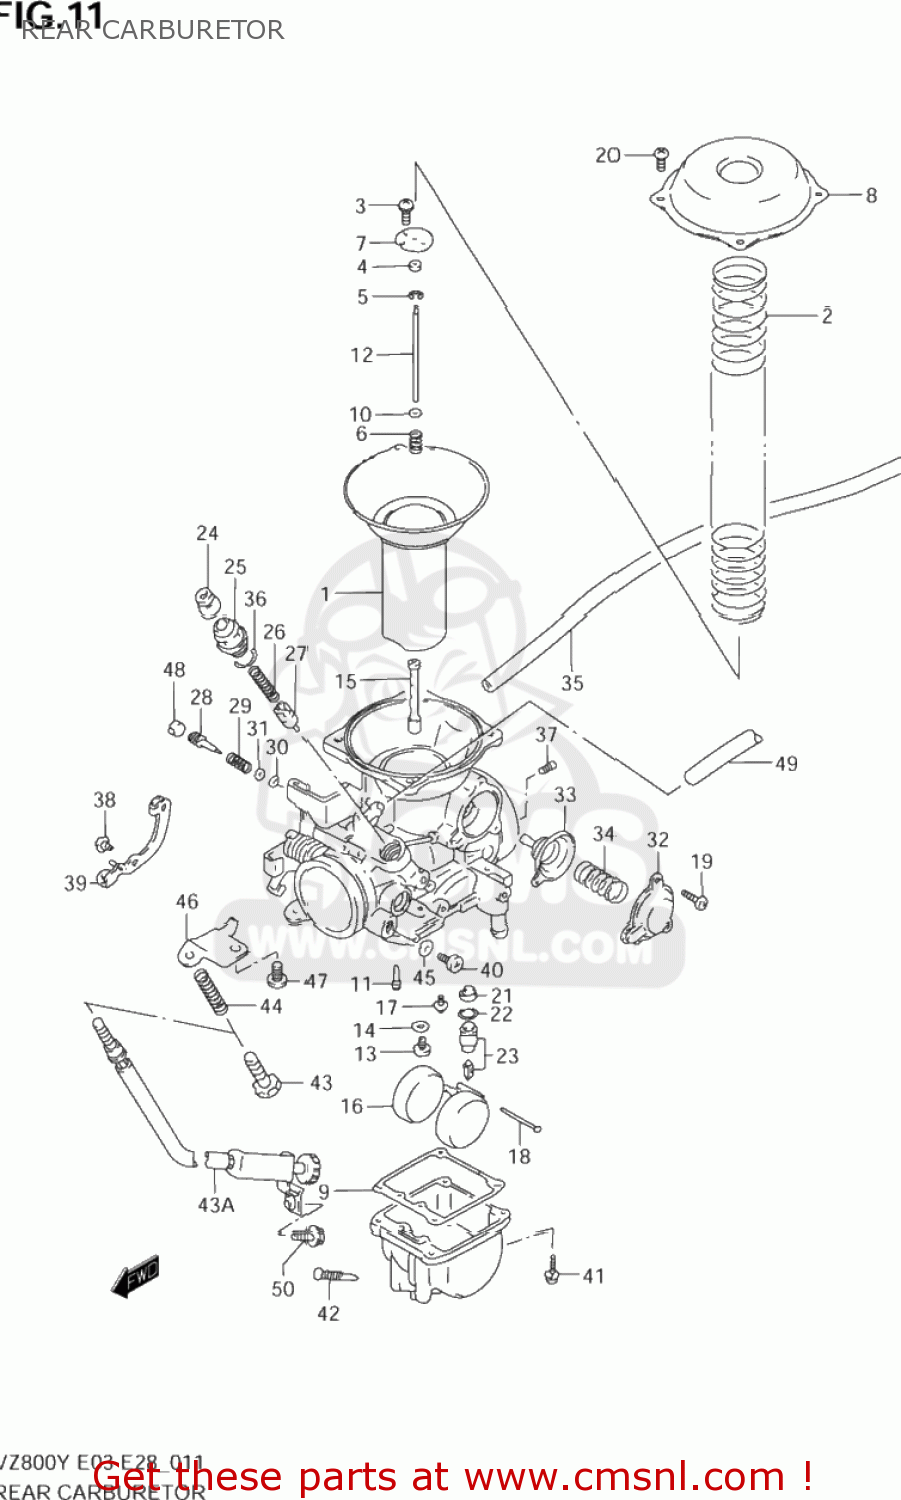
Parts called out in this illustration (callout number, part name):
1	DIAPHRAGM,CARBURETOR
2	SPRING,DIAPHRAGM
3	SCREW
4	RING
5	CLIP
6	SPRING
7	PLATE
8	COVER
9	GASKET,FLOAT CHAMBER (NAS)
10	WASHER
11	JET,PILOT(42.5)
12	NEEDLE,JET(5D83-1)
13	JET,MAIN
14	WASHER
15	JET,NEEDLE(P-3M)
16	FLOAT
17	SCREW
18	PIN,FLOAT
19	SCREW
20	SCREW
21	FILTER
22	O-RING,NEEDLE VALVE
23	VALVE ASSY,NEEDLE
24	CAP
25	HOLDER,GUIDE
26	SPRING
27	PLUNGER,STARTER
28	SCREW,PILOT
29	SPRING
30	O RING,PILOT AIR SCREW
31	WASHER
32	COVER
33	DIAPHRAGM ASSY
34	SPRING
35	HOSE
36	O RING
37	JET,PILOT(70)
38	SCREW
39	LEVER,ASSY
40	SCREW(5X6)
41	SCREW
42	PLUG,DRAIN
43	ADJUSTER
43A	ADJUSTER ASSY
44	SPRING
45	GASKET,DRAIN PLUG (NAS)
46	BRACKET
47	SCREW
48	PLUG
49	(CA) HOSE SET,FUEL
50	BOLT
